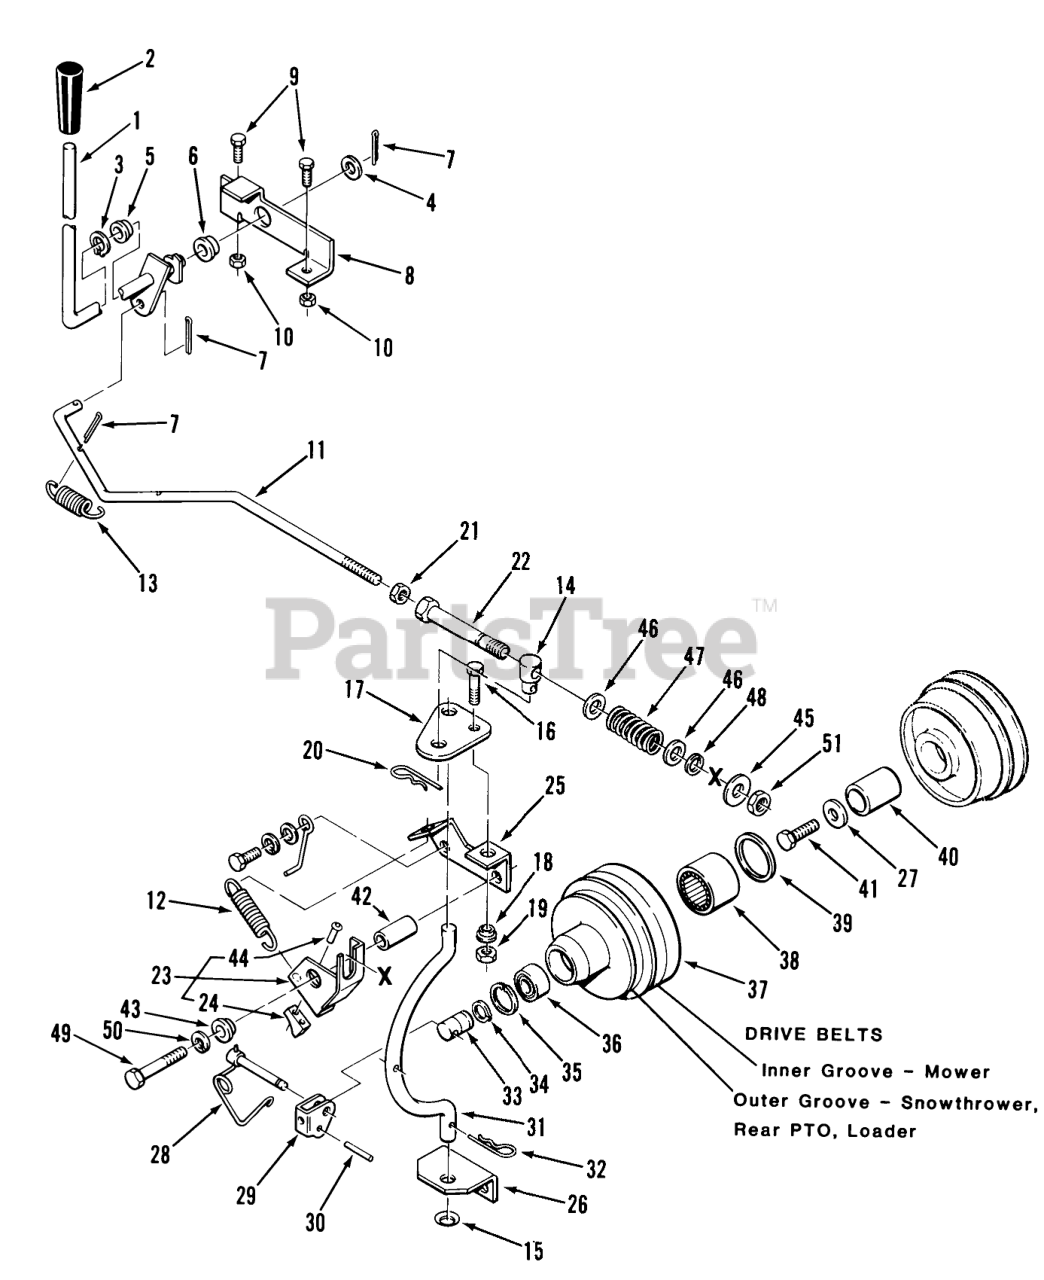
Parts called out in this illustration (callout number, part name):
1	PTO CLUTCH LVR ASM
2	GRIP
3	Grip Ring
4	SHIM-WASHER
5	BUSHING-NYLINER
6	NYLINER BUSHING
7	Pop Rivet
8	SUPPORT-PTO CLUTCH
9	Bolt
10	Nut
11	ROD PTO CLUTCH
12	SPRING EXTENSION
13	SPRING
14	Trunnion
15	RING-REINFORCED CIRC
16	BOLT
17	PTO Plate
18	SPACER-LIFT LINK
19	Nut
20	Hairpin Cotter
21	Nut
22	TUBE-CLUTCH SPACER
23	PTO Brake Assy
24	Brake Pad
25	BRACKET
26	Axle
27	WASHER CONE CLUTCH
28	Pin
29	Clevis
30	PIN-SPIROL
31	ROD HOUSING
32	Hairpin
33	SHAFT-PTO
34	RING-SNAP, EXTERNAL
35	Ring-Snap
36	BEARING-BALL
37	HOUSING CLUTCH
38	BRG-NEEDLE OPEN END
39	SEAL-OIL
40	RACE BEARING
42	Spacer
43	BUSHING PTO PIVOT
44	RIVET-BRASS
45	WASHER
46	Washer
47	SPRING COMPRESSION
48	SNAP RING- 5/8 EXT
49	Bolt 7/16-14 x 3
50	LOCKWASHER
51	Jam Nut 5/8-11
